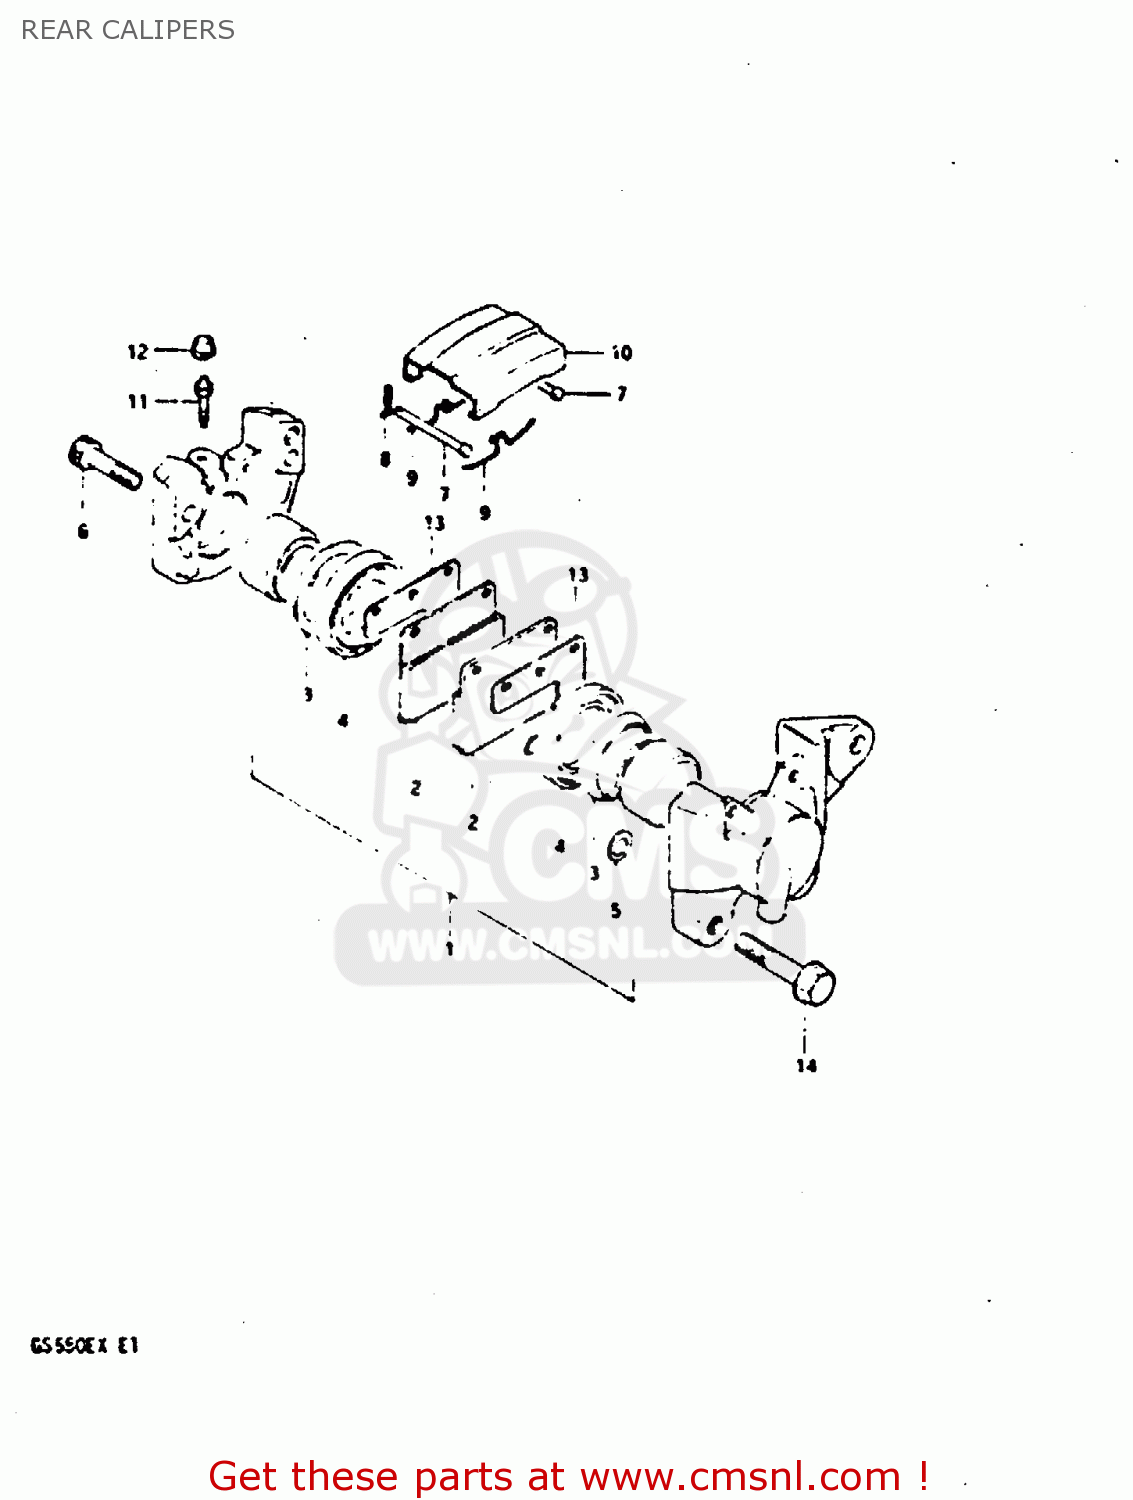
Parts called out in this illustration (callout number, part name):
1	PISTON SET
2	PAD,BRAKE
3	SEAL,PISTON
4	BOOT,PISTON
5	SEAL,JOINT
6	BOLT,CALIPER HOUSING
7	PIN,PAD
8	CLIP,PAD PIN
9	SPRING
10	COVER,DUST
11	BLEEDER
12	CAP,BREATHER
13	SHIM,RR CALIPER
14	BOLT
